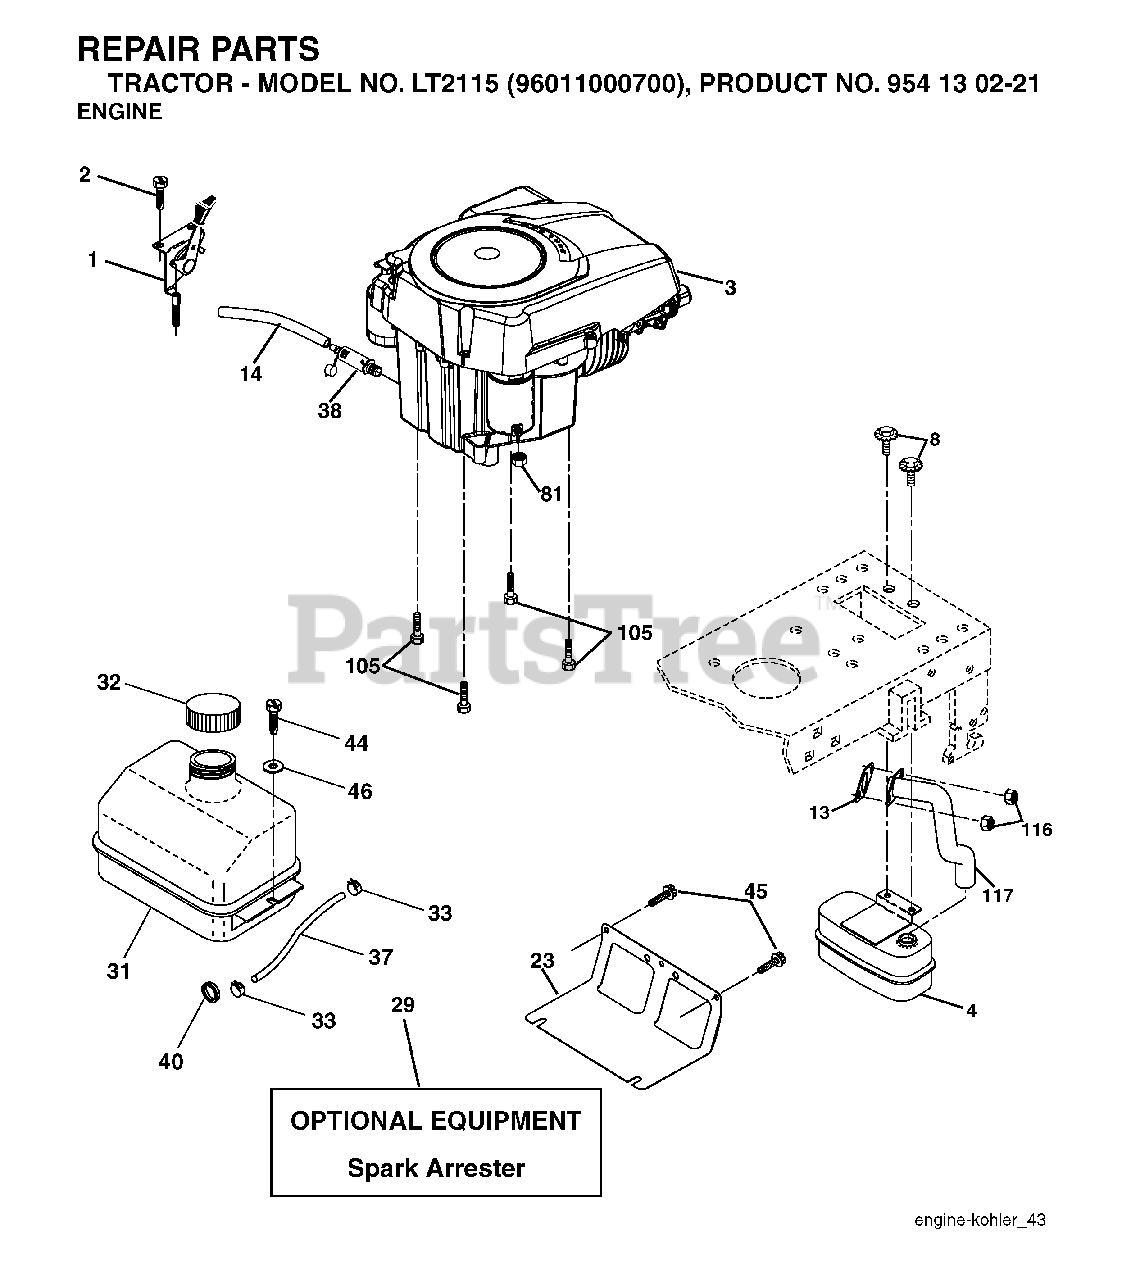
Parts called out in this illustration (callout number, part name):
1	CONTROL.THROTTLE.LT/YT
2	SCREW
4	MUFFLER.SINGLE.CYL.KOHL/B&S
8	BOLT, 5/16-18 X 1 3/4
13	GASKET ENGINE
14	TUBE, DRAIN OIL ASM.
23	SHEILD.BROWNING.DBR.GUARD
29	ARRESTER SPARK (OPTIONAL)
31	TANK FUEL FRONT
32	FUEL CAP
33	HOSE CLAMP
37	LINE.FUEL.20
38	PLUG DRAIN OIL EASY
40	GROMMET T
44	SCREW HEXWSHR 1/4-20X3/4
45	SCREW, 3/8-16X3/4
81	NUT
105	SCREW 3/8-16X1
116	NUT.HEX.FLANGE.TOPLOCK
117	TUBE EXHAUST
